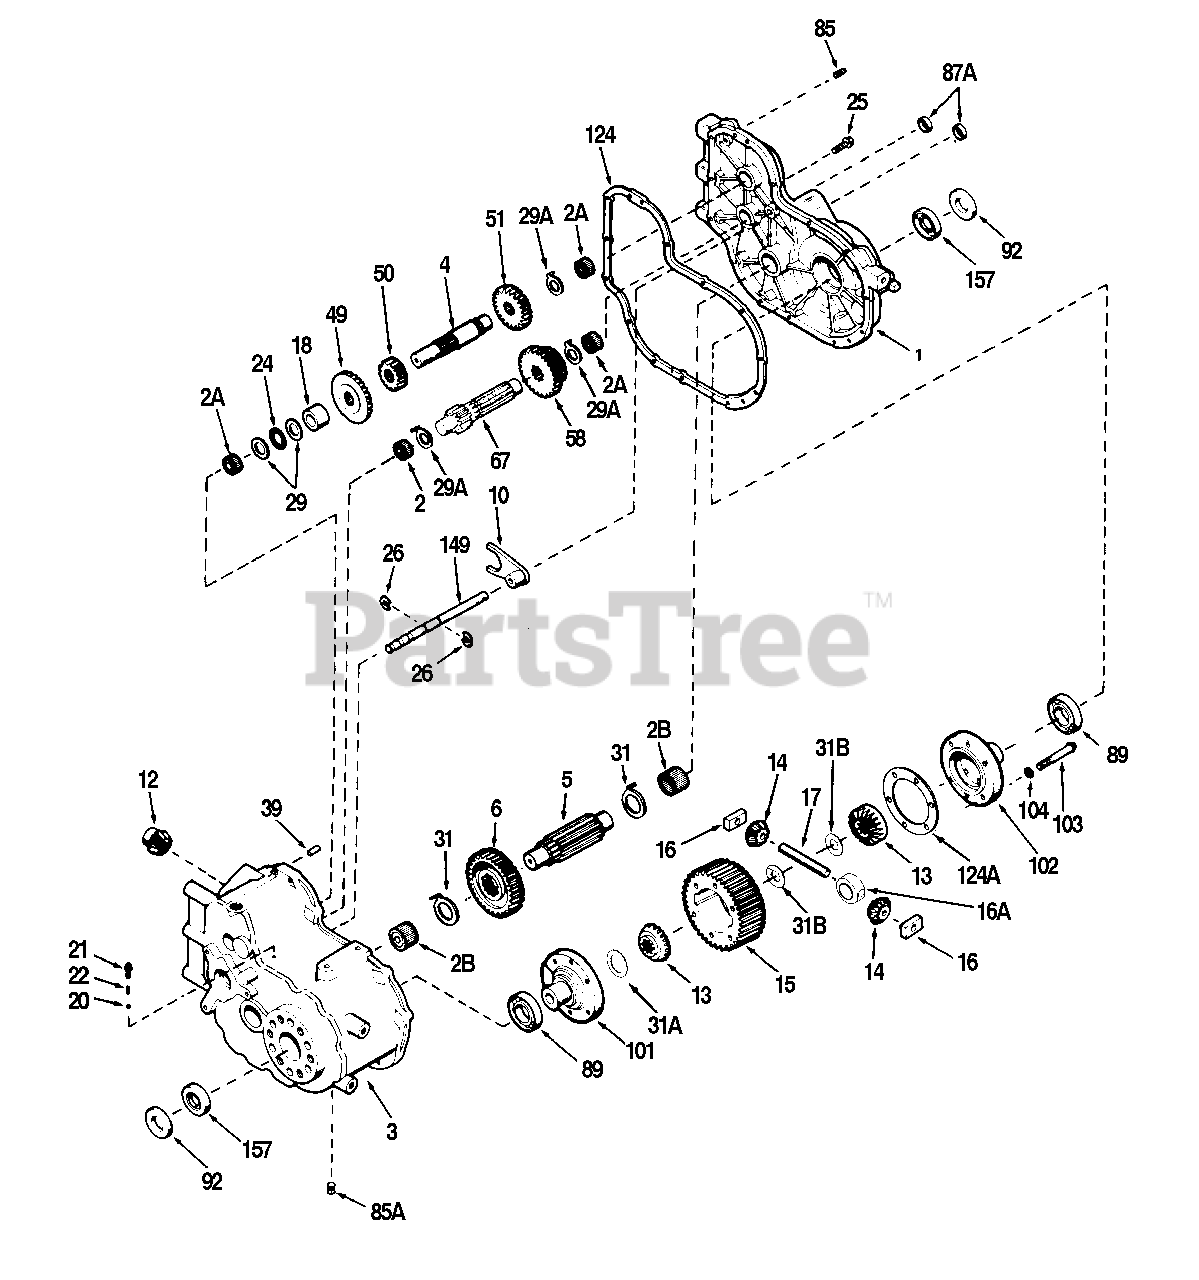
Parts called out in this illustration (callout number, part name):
1	TRANSAXLE COVER
2	NEEDLE BEARING
2A	NEEDLE BEARING
2B	NEEDLE BEARING
3	TRANSAXLE CASE
4	COUNTERSHAFT
5	OUTPUT PINION
6	OUTPUT GEAR (37 teeth)
10	SHIFT FORK
12	BEVEL PINION
13	BEVEL GEAR (16 teeth)
14	BEVEL PINION (10 teeth)
15	RING GEAR
16	DRIVE BLOCK
16A	SPACER BLOCK
17	DRIVE PIN
20	Ball, 3/16" dia.
21	SCREW, 1/4-20 x 5/8
22	DETENT SPRING
24	THRUST BEARING
25	SCREW, 5/16-18 x 1"
26	RETAINING RING
31B	BELLEVILLE WASHER
39	DOWEL PIN
49	BEVEL GEAR (30 teeth)
50	SPUR GEAR (16 teeth)
51	SPUR GEAR (20 teeth)
58	SHIFTER GEAR (23 & 27 teeth)
67	SHIFTER SHAFT
85	PLUG, 1/8-27
85A	MAGNETIC DRAIN PLUG, 3/8-18
87A	OIL SEAL, 1/2"
89	BALL BEARING
101	DIFFERENTIAL CARRIER
102	DIFFERENTIAL CARRIER
103	SCREW, 3/8-16 x 2-3/4"
104	LOCKWASHER, 3/8"
149	SHIFT ROD (High-Low)
157	OIL SEAL 1-1/8"
